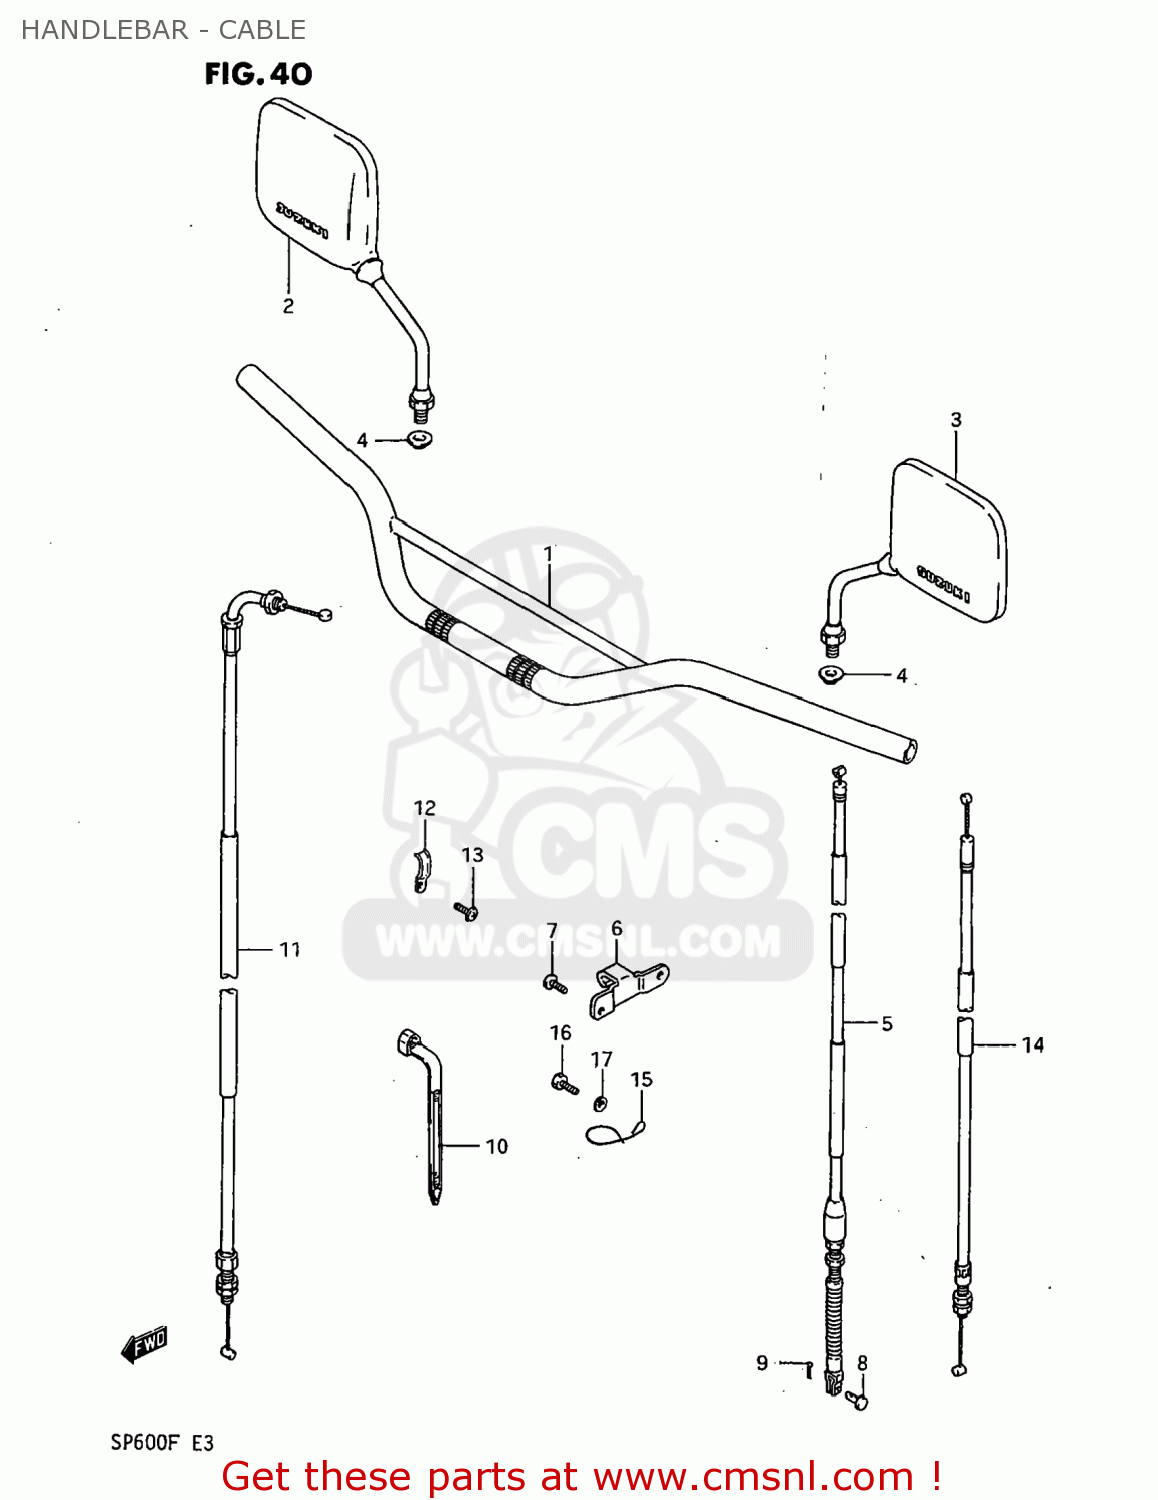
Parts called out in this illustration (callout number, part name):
1	HANDLEBAR
2	MIRROR ASSEMBLY,REAR VIEW
3	MIRROR ASSEMBLY,LEFT
4	WASHER
5	CABLE ASSY,CLUTCH
6	STOPPER,CLUTCH CABLE
7	SCREW
8	PIN(L:13)
9	PIN
10	CLAMP(L:125)
11	CABLE ASSEMBLY,THROTTLE
12	CLAMP
13	SCREW
14	CABLE ASSY,DECOMP
15	GUIDE
16	BOLT
17	WASHER,LOCK
